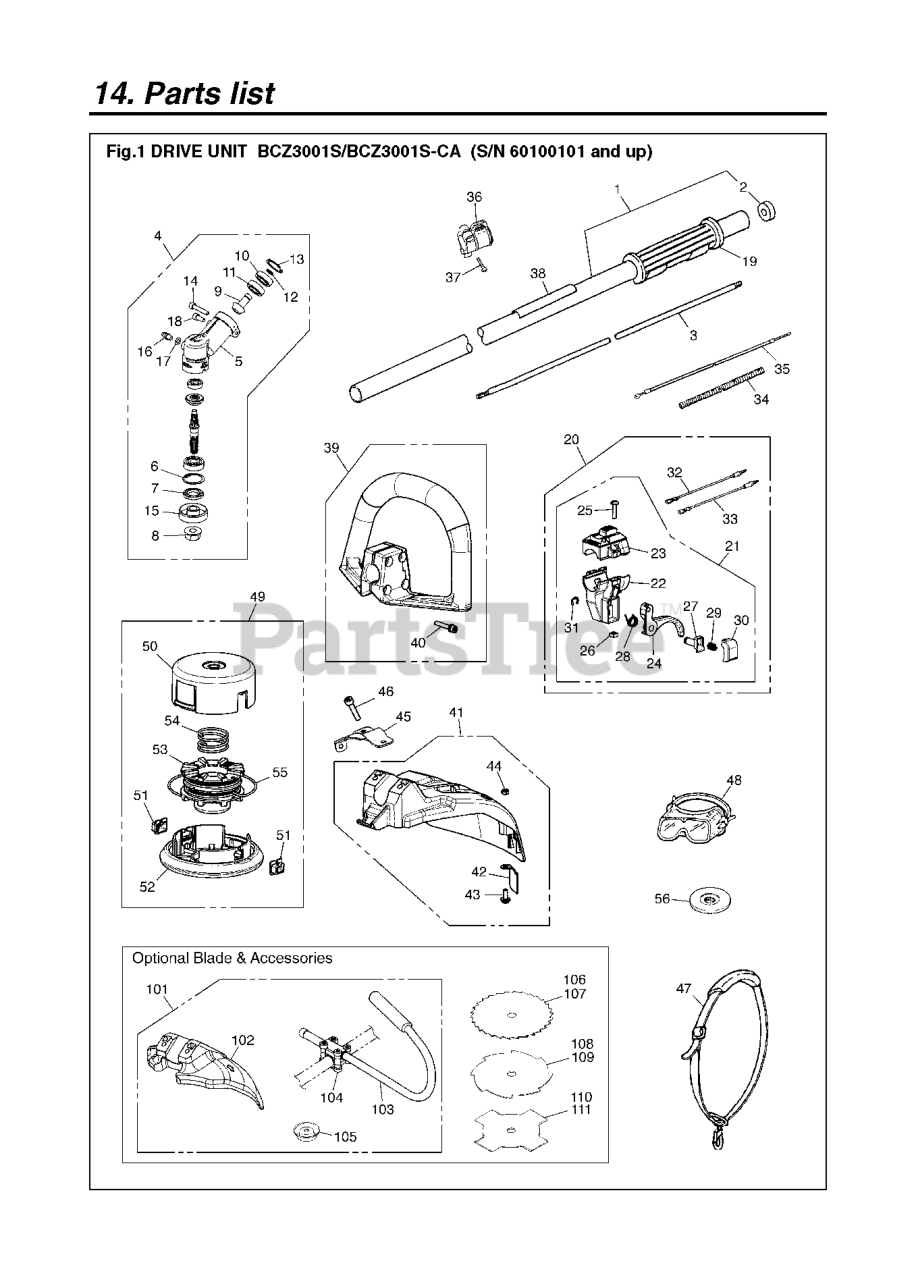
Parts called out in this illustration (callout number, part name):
1	PIPE COMP
4	RP_GEARCASE ASSY.
5	GEARCASE
6	RING,SNAP M26x1.2 RP-318013340
11	BALL BEARING
13	RP_RING
14	BOLT TORX
15	HOLDER(A)
16	FITTING
18	BOLT, TORX
20	LEVER COMP (RPLS 8488R20343)
21	LEVER (FLEX. LEVER)(RPLS -13)
22	STAY
23	COVER COMP (RPLS 611014410-02)
24	THROTTLE TRIGGER
32	CORD (A), BLACK
33	CORD (B), RED
36	HANGER COMP.
37	SCREW
39	HANDLE ASSY. (RPLS T319514001)
40	SCREW
41	GUARD COMP
42	BLADE (RPLS T300224120)
43	SCREW
46	BOLT, TORX
47	STRAP ASSY
48	GOGGLExxx (RPLS
49	4" TAP TRIMMER HEAD PT104
50	CASE (RPLS T318915111)***
52	COVER (RPLS T318915131)
53	HOLDER, CORD (RPLS T318915141)
56	HOLDER (B)
101	BLADE KITBCZ3000S
103	HANDLE(L)
104	BRACKET ASSY.
105	COVER (10MM)
106	Brushcutter Blade, 22 Tooth 9"
107	Brushcutter Blade, 24 Tooth 9"
108	BLADE, 8
109	Brushcutter Blade, 8 Tooth 9"
110	BLADE, 8
111	Brushcutter Blade, 4 Tooth 9"
